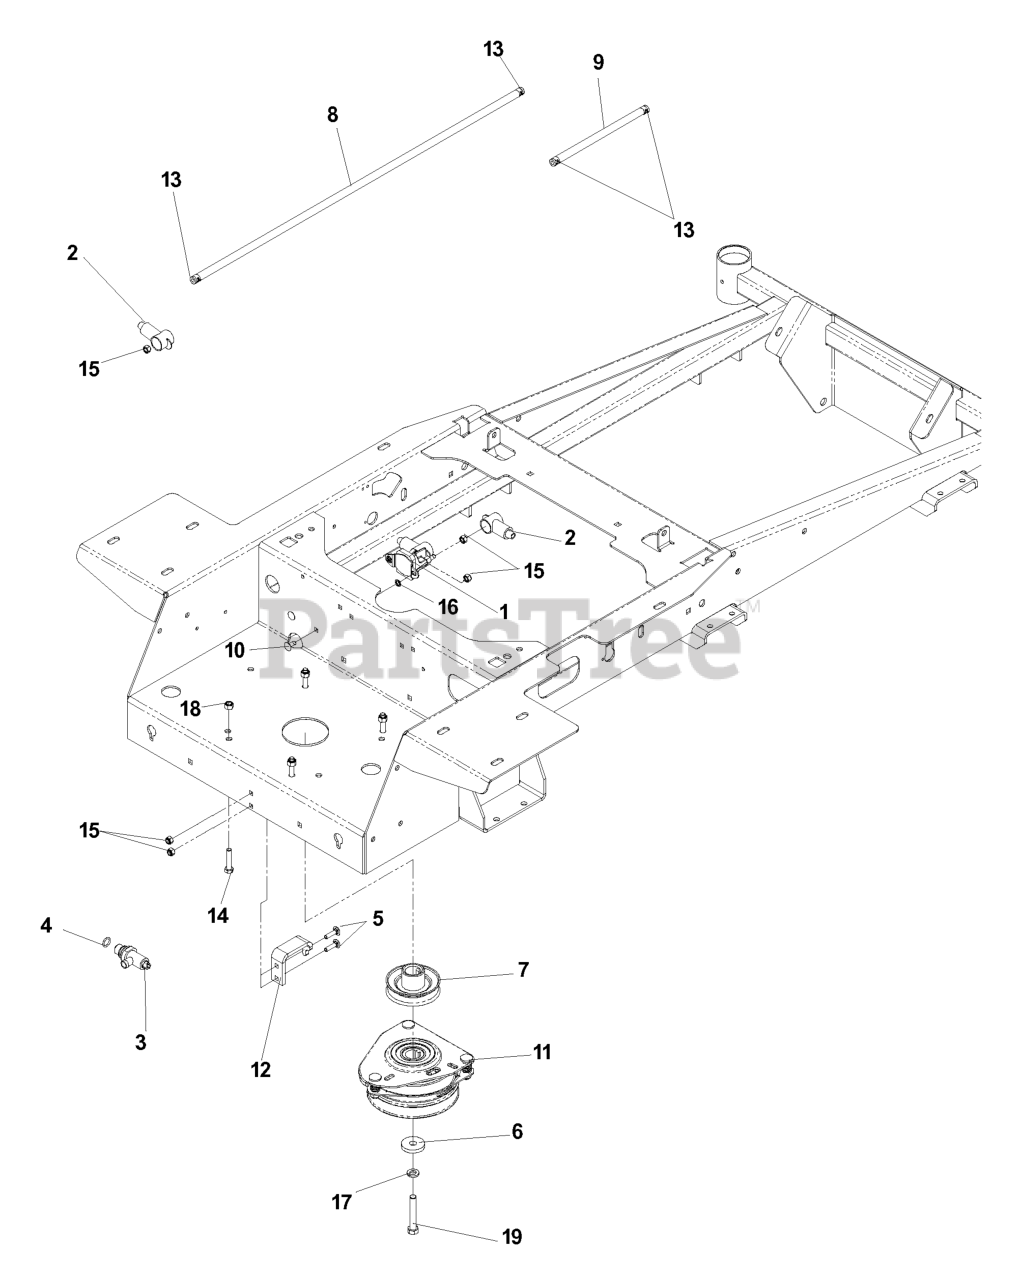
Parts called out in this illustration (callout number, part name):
3	VALVE ASSEMBLY
5	RHSNB, 1/4-20 X 1, GR5
6	CLUTCH, WASHER
8	FUEL LINE 24"
9	FUEL LINE 5"
10	RHSSNB, 1/4-20X5/8
12	CLUTCH TIE DOWN
13	HOSE CLAMP
14	CAPSCREW 5/16 X 1/1/2 HEX HEAD
15	NUT.1/4-20.HEX.NYLOC.ZD
16	WASHER 1/4 INT TOOTH
17	WASHER 7/16 LOCK
18	NUT 5/16 NYLOC
19	BOLT 7/16F X 2 1/2
